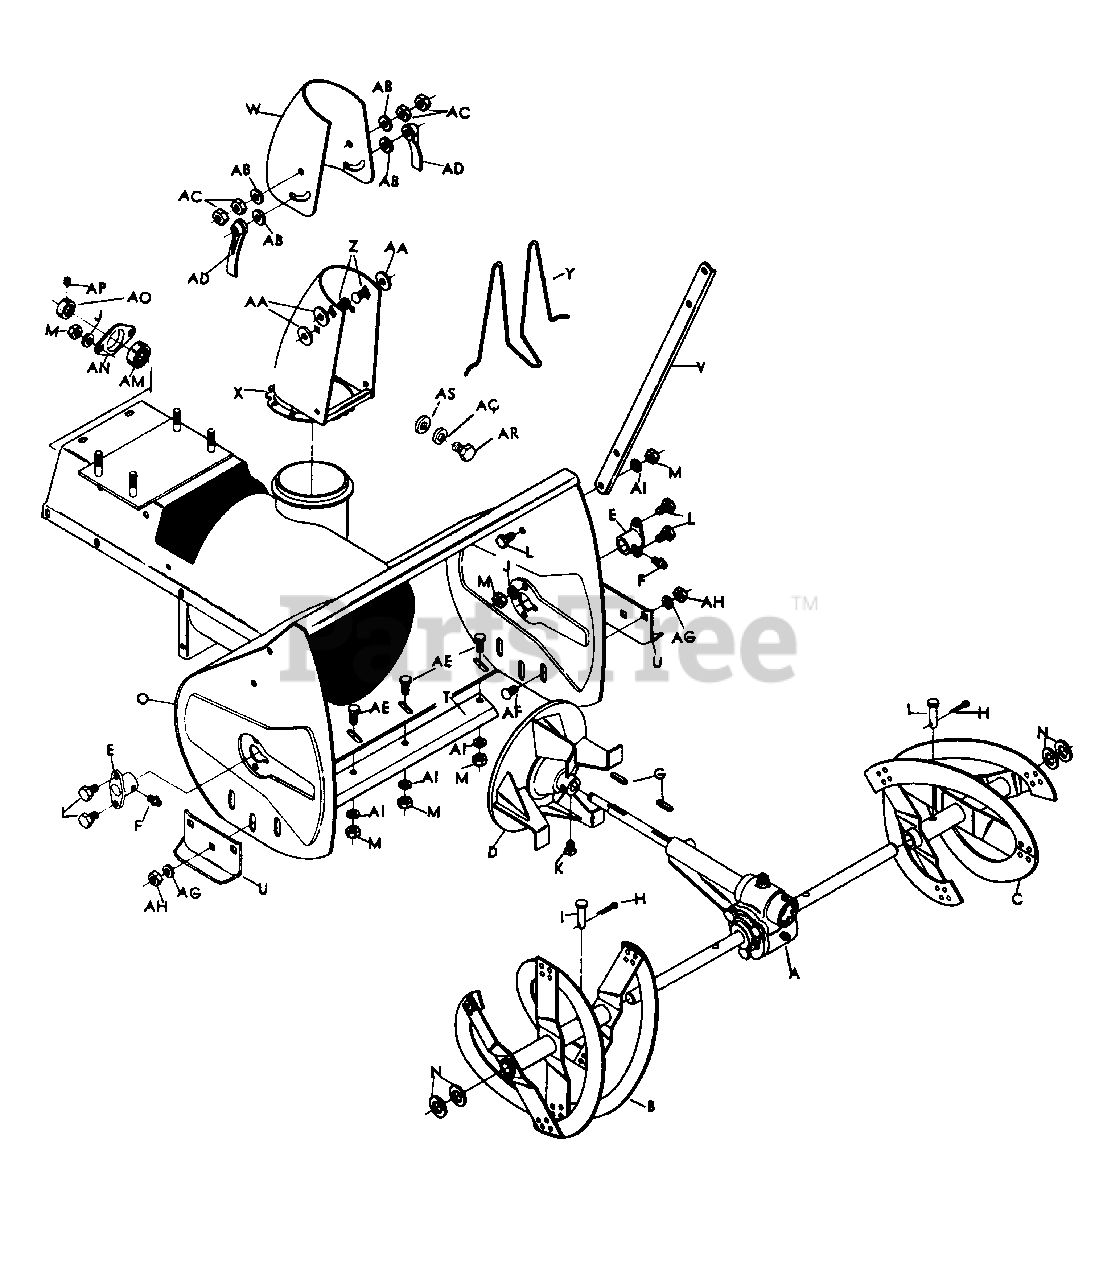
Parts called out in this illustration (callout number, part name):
A	Gear Case Ass'y.-Breakdown on RIDER MOWER FRONT END GROUP (MODELS 9329, 9329E, 9329ES, 9369, 9369E & 9369ES) PARTS LIST
B	Auger Assembly-R.H.
C	Auger Assembly-L.H.
D	Impeller Assembly
E	Auger Bearing
F	Grease Fitting
H	1/8 x 3/4 Cotter Pin-Pl
I	Shear Pin
J	5/16 Lockwasher
K	3/8-16 x 1/2 Sq. Hd. Setscrew, Cup Pt.
L	5/16-18 x 3/4 Hex Hd. Capscrew-Pl.
M	5/16-18 Hex Nut-Pl.
N	Washer
T	Scraper Blade
U	Skid
V	Drift Cutter
W	Chute Deflector
X	Chute & Ring Assembly
Y	Chute Guard
Z	3/8-16 x 1 Short Neck Carriage Bolt-Pl.
AA	1/2 Flat Washer-Pl.
AB	3/8 Flat Washer-Pl.
AC	3/8-16 Hex Jam Nut-Pl.
AD	Wing Nut
AE	5/16-18 x 3/4 Wafer Hd. Bolt-Pl.
AF	3/8-16 x 3/4 Carriage Bolt-Pl.
AG	3/8 Lockwasher-Pl.
AH	3/8-16 Hex Nut-Pl.
AI	5/16 Lockwasher-Pl.
AM	Bearing
AN	Stamping
AO	Collar w/Setscrew
AP	1/4-20 x 1/4 Socket Setscrew
AQ	1/4 Lockwasher-Pl.
AR	1/4-20 x 3/4 Hex Hd. Capscrew-Pl.
AS	1/4 SAE Flat Washer-Pl.
